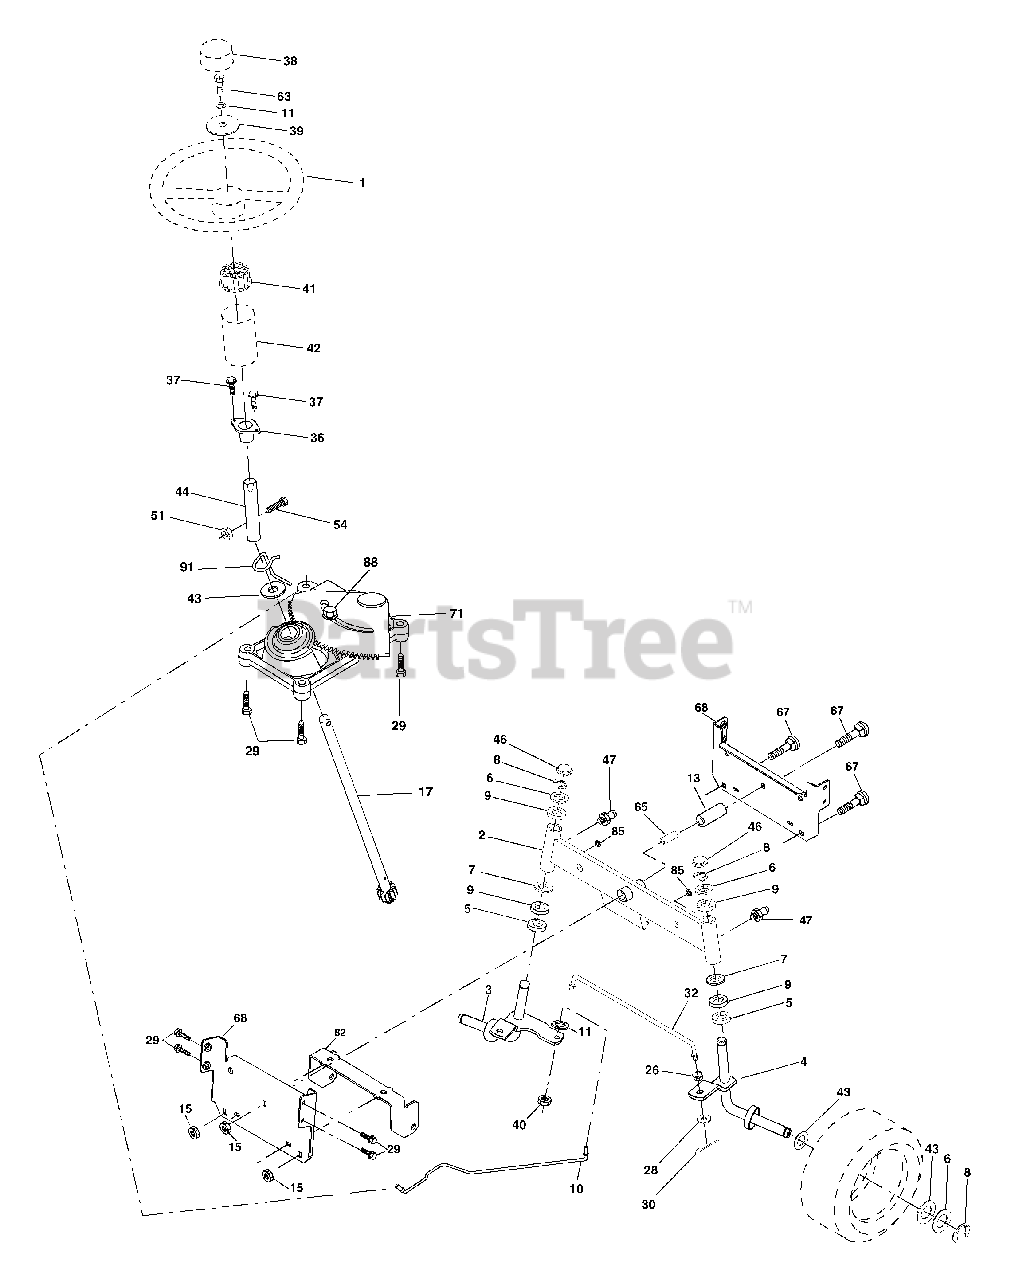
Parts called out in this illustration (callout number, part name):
1	Wheel Steering Ayp/P/L Blk
2	Axle Asm
3	Spindle Asm LH
4	Spindle Asm RH
5	Bearing Race Thrust Harden
6	Washer 25/32 x 1-5/8 x 16 Ga
7	Washer 27/32 x 1-1/4 x 16 Ga
8	Ring Klip #t5304-75
9	Bearing Col Strg Blk
10	Link Drag
11	Washer Lock Hvy Hlcl Spr 3/8
13	Spacer earing Axle Front
15	Hexflange Lock
17	Shaft Asm Strg
26	Bushing Link Drag Blk LR
28	Washer 13/32 x 7/8 x 16 Ga
29	Screw 3/8-16 x 3/4
30	Pin Cotter 1/8 x 3/4 Cad
32	Rod Tie Wire Form 19 75 Mech
36	Bushing Strg 5/8 Id Dash
37	Screw
38	Cap Wheel Steer Ayp
39	Washer 13/32 x 2-3/8 x 12 Ga.
40	Nut Lock Center 3/8-24un
41	Adaptor Wheel Strg
42	Boot Dash Mtl Steering Blk
43	Washer 25/32 X 1 1/4 X 16 Ga
44	Extension Steering
46	Cap Spindle Fr Top Blk
47	Fitting Grease
51	Nut Lock Hex W/Ins 5/16-18
54	Bolt Fin Hex 3/8-16unc x 1-1/4
63	Bolt Fin Hex 3/8-16unc x 1 Gr.5
65	Spacer Brace Axle
67	Bolt Fin Hex 5/8-11 unc x 2-3/4
68	Brace Axle
71	Steering Asm.
82	Bracket Susp Chassis Front
85	Fastener Christmas Tree
88	Bolt Shoulder 7/16-20
91	Clip Steering
